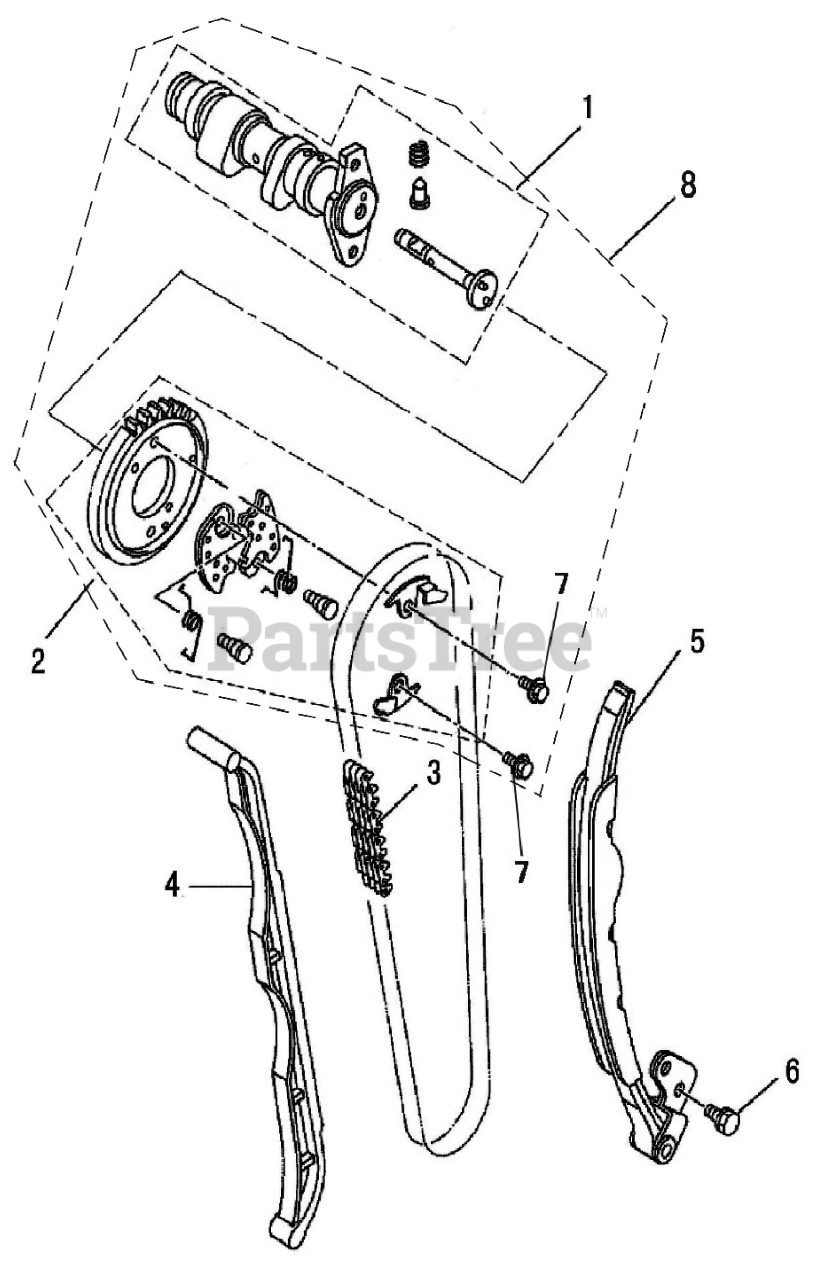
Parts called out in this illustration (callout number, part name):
1	Camshaft assy
2	Timing Driven Sprocket assy
3	Timing Chain M7-6.35-130
4	Guide Plate
5	Tensioner Plate
6	Hex head bolt & plain washer M6x16
7	Hex flange bolts M7x11
8	Camshaft Assembly
